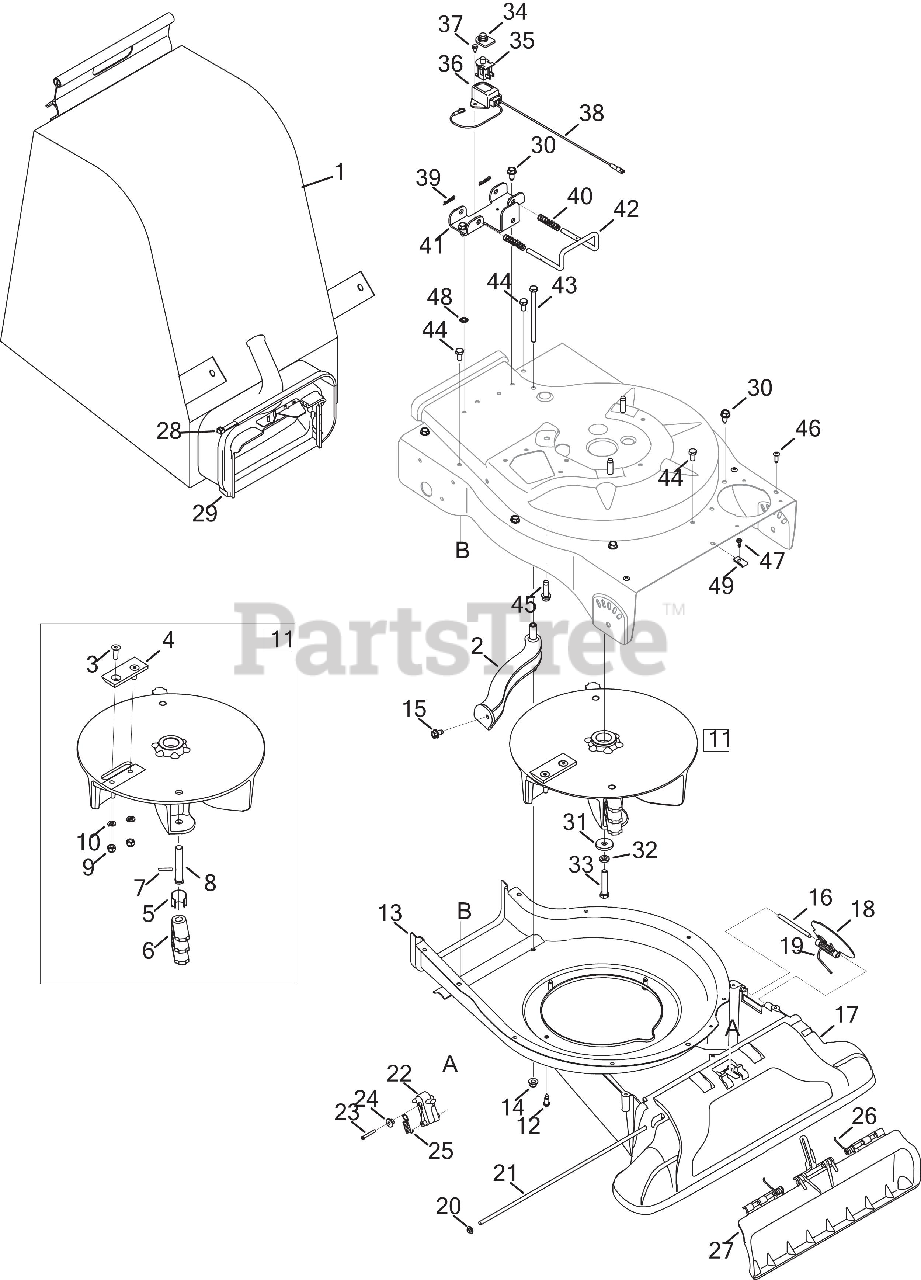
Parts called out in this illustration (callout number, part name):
1	Bag Assembly (incl. Ref 28)
2	Screen Assembly
3	Hex Screw 5/16-24 x 1.0
4	Chipper Blade
7	Spiral Pin
8	Clevis Pin
9	Lock Nut, 5/16-24
10	Lock Washer, 5/16
11	Impeller Assembly (Incl. Ref.# 3 – 10)
12	Shoulder Screw, #12-24 x.30 x.46
13	Lower Flail Housing
14	Flange Lock Nut 5/16-18
15	Screw, 5/16-18 x.500
18	Base Adapter Door
19	Torsion Spring
20	Cap Speed Nut 1/4
21	Pivot Rod
22	Nozzle Door Lever
23	Hex Screw, #8-18 x 1.25
24	Shoulder Spacer
25	Extension Spring
26	Nozzle Door Torsion Spring
27	Nozzle Door
28	Tie Strap, 42”
29	Chute Assembly
30	Hex Index Screw, 5/16-12 x.750
31	Flat Washer.375 ID x 1.25 OD
32	Lock Washer 3/8
33	Hex Cap Screw 3/8-24 x 2.0
34	Switch Cover
35	Safety Switch
36	Safety Switch Cover
37	Hex Washer Screw #10-16 x.50
38	Wire Harness
39	Cotter Pin
40	Compression Spring
41	Mounting Bracket
43	Hex Cap Screw 5/16-18 x 4.5
44	Hex Cap Screw 5/16-18 x.625
45	Hex Washer Screw 3/8-16 x 1.00
46	Screw, #12-16 x.750
47	Screw #10 - 16 x.500
48	External L-Washer 5/16
49	Speed Nut
